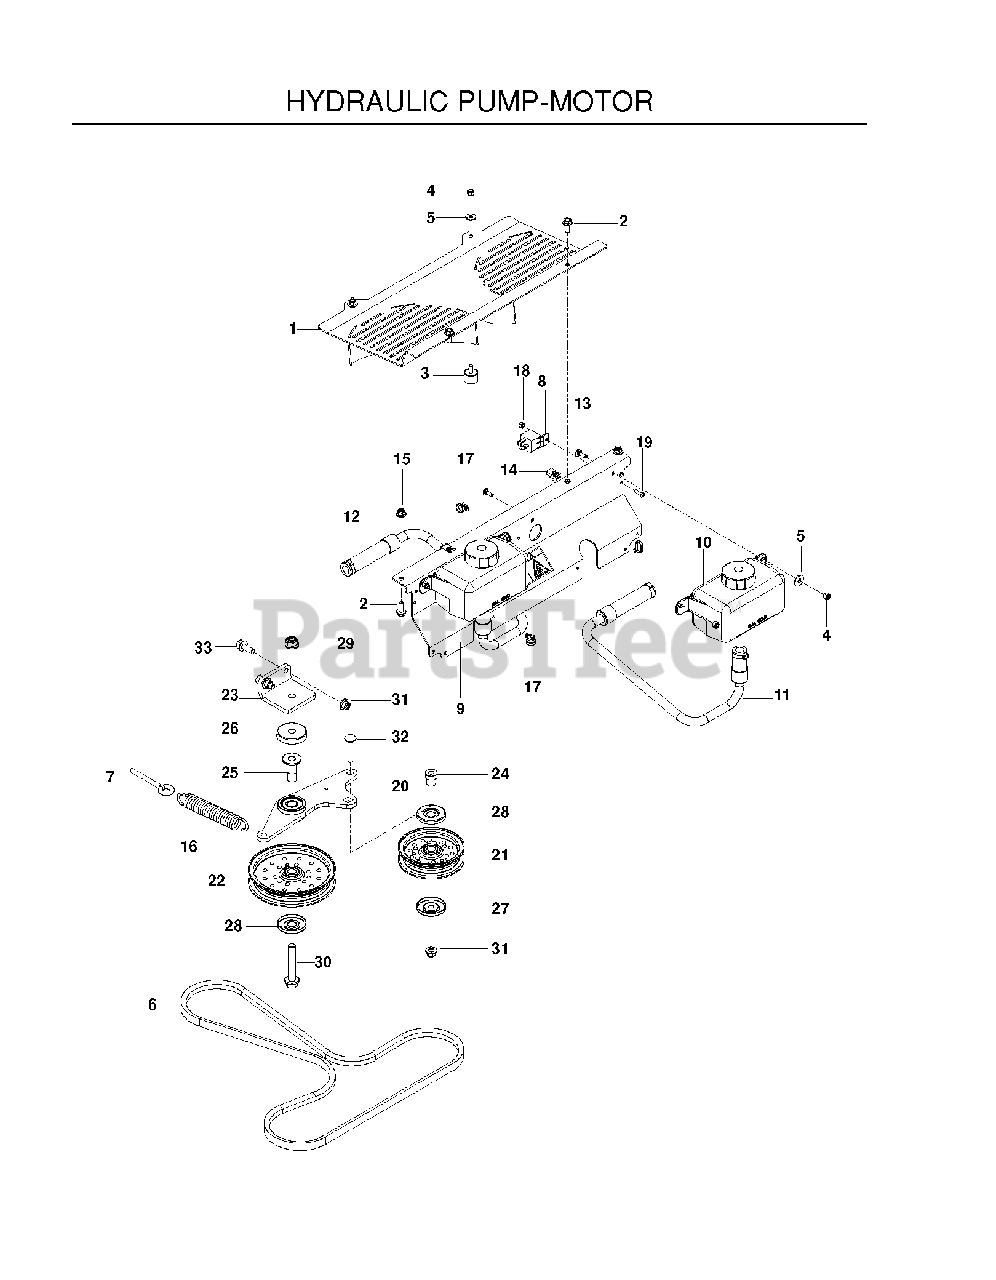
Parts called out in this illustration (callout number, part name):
1	SHIELD, FAN
2	HHFS 5/16-18 X 3/4
3	BUMPER, MALE STUD, 1/4-20
4	RP_NUT 1/4-20 NYLOC
5	WASHER 1/4 FLAT
6	BELT, BX, 72.3
7	EYE BOLT 5/16 X 3.50
9	MOUNT, EXPANSION TANK, BLK
10	HG_TANK, EXPANSION
11	HOSE, EXPANSION TANK, RT
12	HOSE, EXPANSION TANK, LT
13	RHSNB 1/4C X 3/4
14	U-CLIP 5/16-18 NUT RETAINER
15	5/16-18 NYLOC FLANGE NUT
16	SPRING, EXTENSION
17	OPTICAL REV COUNTER (TACHOMETE
18	NUT 10-24 NYLOC
19	SCR #10-24 X .75 SKT HD BLK
20	ARM, IDLER W/BEARING
21	IDLER PULLEY
22	IDLER, FLAT, 5.5"
23	MOUNT, IDLER ARM, BLACK
24	PIVOT, IDLER
25	BUSHING, PIVOT
26	SHIELD, DUST
27	DUST SHIELD
28	SHIELD, DUST
29	NUT, 1/2-13 HEX FLG NYLOC ZD
30	HFFS 1/2-13 X 3 GD 5 ZD
31	NUT 3/8-16 HEX FLG NYLOC ZD
32	RHSNB 3/8C X 2
33	HHFS 3/8-16 X 1 GRD 5 ZD
